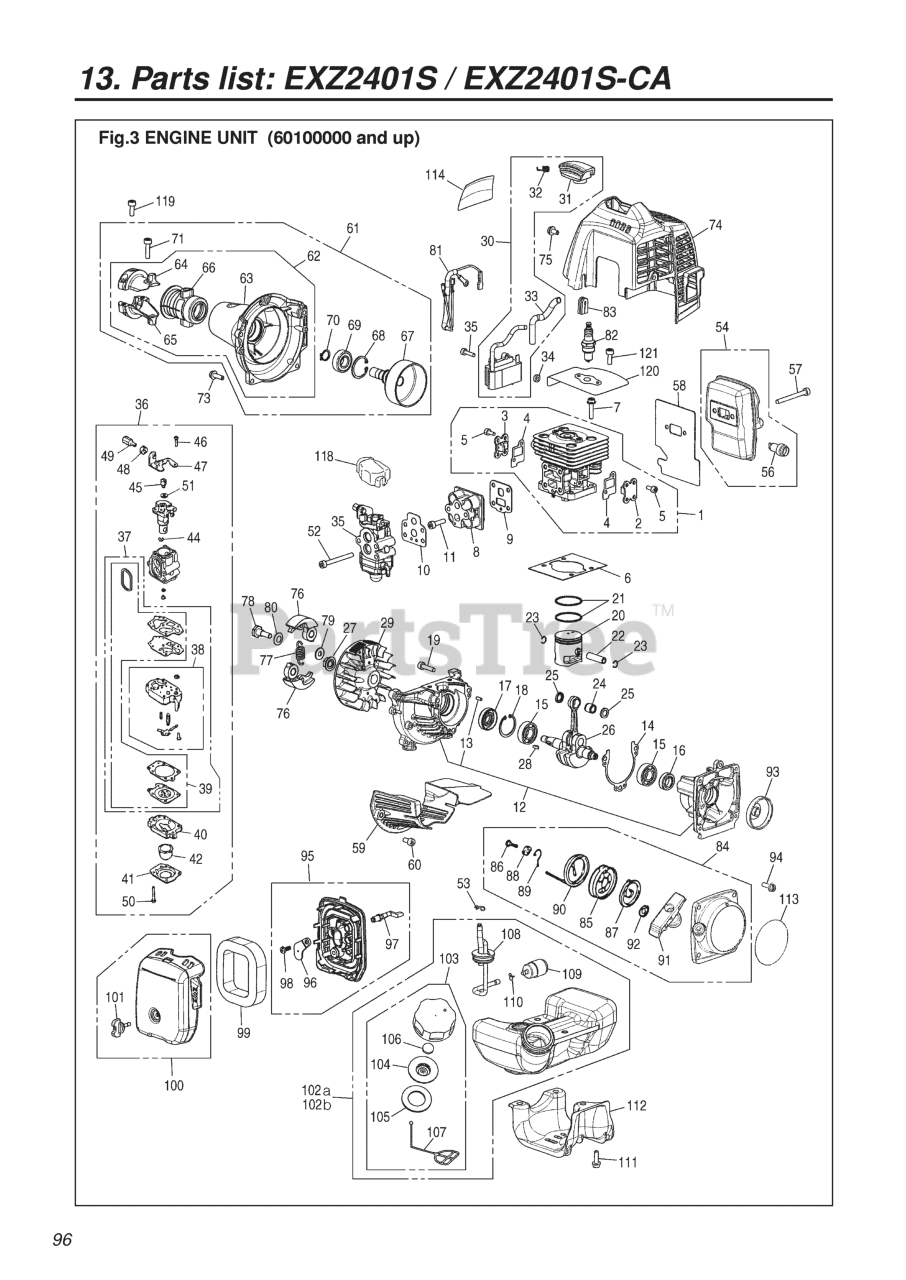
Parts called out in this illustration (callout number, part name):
1	CYLINDER-C
2	COVER, TR-S
3	COVER, TR-F
4	GASKET, TR
5	BOLT, TORX
6	GASKET, BASE
7	BOLT
8	INSULATOR
9	GASKET, INSULATOR
10	GASKET, CARB
11	BOLT, TORX
12	CRANKCASE-C
13	PIN
14	GASKET, CASE
15	BEARING
16	SEAL
17	SEAL, OIL (RPLS 1140-21220)
18	RING, SNAP, M28 x 1.2
19	BOLT (RPLS 2850-14220)
20	PISTON
21	RING, PISTON
22	PIN, PISTON
23	RING, SNAP (RPLS 1101-41320)
24	BEARING
25	WASHER
26	CRANKSHAFT-C
28	KEY
29	ROTOR
30	COIL-A
31	CAP (RPLS 4810-72110)
32	SPRING
33	TUBE
34	SPACER (RPLS -71260)
35	BOLT TORX
36	CARBURETOR ASSY
37	REBUILD KIT
38	BODY, PUMP
39	KIT, GASKET (REPLACES-06020)
40	BODY, PURGE
41	COVER, PUMP
42	PUMP, PRIMING
44	RING
45	SWIVEL
46	SCREW
48	NUT, CABLE ADJUSTER
49	SCREW, CABLE ADJUSTER
50	SCREW
51	WASHER
52	BOLT
53	CLIP
54	MUFFLER-A
56	ARRESTER
57	BOLT
58	GASKET, MUFFLER
59	PLATE
60	BOLT
61	HOUSING ASSY (RPLS T1551-31000
62	HOUSING COMP (RPLS. -31110)
64	BRACKET (A) (RPLS -31211)
65	BRACKET (B)
66	CUSHION (RPLS -31231)
67	DRUM (REPLACES 4810-31122)
68	RING, SNAP, M28 x 1.2
69	BEARING
70	RING, SNAP (RPLS 3130-13270)
71	BOLT (RPLS 2850-14220)
73	BOLT
74	COVER, ENGINE
75	BOLT (RPLS. T4950-51011)
76	SHOE
77	SPRING
78	BOLT
79	WASHER, FLAT (USE 182303)
80	WASHER (RPLS -51241)
81	CORD COMP.
83	GROMMET
84	RECOIL-A
85	REEL
86	SCREW
87	SPRING, SPIRAL
88	COLLAR
89	ARM
90	ROPE (REPLACES 4500-75160)
91	KNOB (RPLS -75420)
92	PLATE, STOPPER
93	PULLEY
94	BOLT, TORX
95	BODY ASSY (RPLS T1551-82100)
96	PLATE, CHOKE
97	LEVER
98	SCREW
99	ELEMENT
100	COVER-A (RPLS T1551-82200)
101	KNOB
102A	TANK ASSY
103	CAP ASSY (RPLS -85201)
104	HOLDER (REPLACES -85230)
105	PACKING
106	FILTER
107	STOPPER
109	FILTER ASSY
110	CLIP
111	BOLT
112	GUARD, TANK
113	LABEL, RECOIL
114	LABEL, COVER
118	COVER
119	BOLT
120	PLATE
121	BOLT
